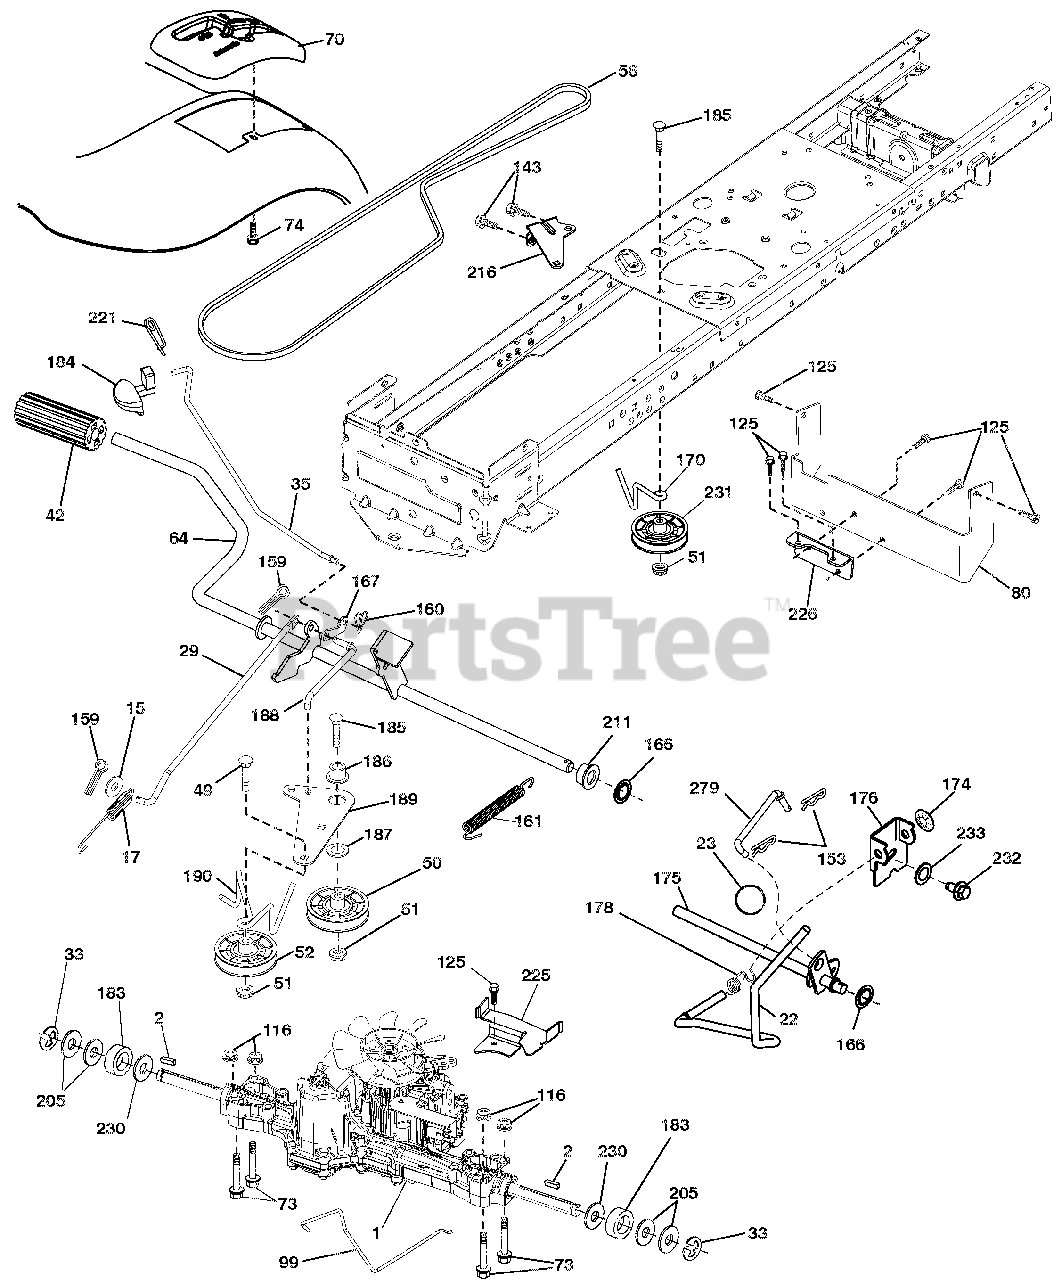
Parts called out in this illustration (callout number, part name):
1	TRANSAXLE, TUFFTORQ K46AW (ORDER PARTS FROM TRANSAXLE MANUFACTURER)
2	KEY.SQUARE.2.0 X .1845/.1865
15	WASHER.13/32 X 13/16 X 16 GA.
17	SPRING.BRAKE.K46.GREEN
22	ROD.SHIFT.FENDER.TLT.2006
23	KNOB DELUXE
29	ROD.BRAKE.K46
33	E-RING.#5133-75
35	ROD.BRAKE.PARKING.LT.TEX
42	COVER.PEDAL.BLK.ROUND
49	BOLT.RDHD.3/8-16UNCX1-3/4.GR5
50	IDLER.FLAT.910"OFFSET
51	Nut, Hex, Flangelock 3/8-16
52	IDLER.V-GROOVE.910"OFFSET
56	V-BELT.MOWER.92.40.42/K46
64	SHAFT ASM.PEDAL.BRAKE CONTROL
70	CONSOLE.SHIFT.STL.HYD.BLACK.TX
73	BOLT.HEX.FLGHD.5/16-18.GR.5
74	SCREW.HEX.WSH.HI-LO.1/4X1/2UNC
80	STRAP.TORQUE.K46/18"TEX
99	ROD.SPRING.BYPASS.K46.LT.Z
116	Nut, Lock Hex Flange 5/16-18 u
125	SCREW.5/16-18X3/4.SMGML.TAP/BL
143	SCREW.THDROL.5/16-18 X 1/2TYTT
153	Retainer Spring
159	PIN.COTTER.1/8 X 3/4.CAD.
160	RETAINER.CLIP(M).DIA.290
161	SPRING.RETURN.CLUTCH.6.75
166	Nut Push .625
167	LATCH.BRAKE.PARKING
170	KEEPER.CENTER SPAN.1.688
174	NUT.PUSH..500
175	SHAFT ASM.SHIFT.T2/K66.FS.TX
176	ARM.CLEVIS.ROD.SHIFT
178	SPRING.SHIFT.GT.2006
183	SPACER.AXLE.HYDRO/PEERLES
184	HANDLE.PARKING BRAKE.LTTEX.505
185	BOLT.RDHD.3/8-16UNC X2-3/4 GR5
186	SPACER.RETAINER
187	WASHER.13/32 X 2 X 10 GA.
188	LINK.CLUTCH.GROUND DRIVE
189	BELLCRANK.GROUNDRIVE.NSTG/NSTL
190	KEEPER.BELLCRANK.DRIVE.GROUND
205	WASHER.25/32 X 1-5/8 X 16GA.
211	BUSHING.SHAFT.BRAKE.HAND CONTR
216	BRACKET.PULLEY.IDLER.WTEX
221	RETAINER.SPRING.CLIP.HANDLE
225	KEEPER.BELT.TRANSAXLE.K46
226	BRACKET.MOUNT.TORQUE.K46.TLT
230	WASHER.HARDEN..793 X 1.637X060
231	IDLER.V-GROOVE.1.688"OFFSET
232	BOLT.FIN HEX.7/16-14X1 GR5
233	WASHER.SERRATED
279	LINK SHIFT T/A
